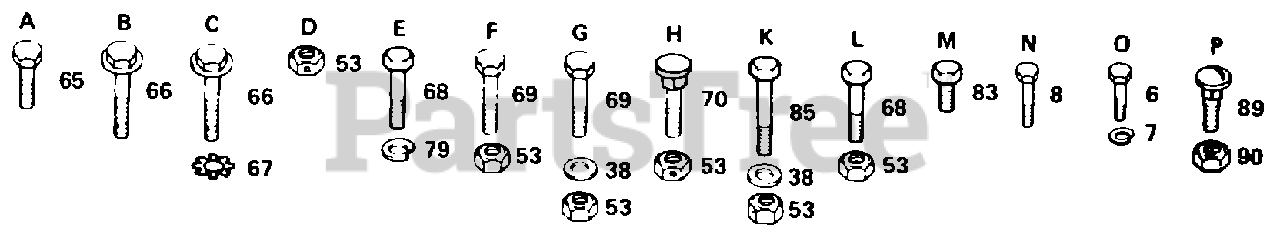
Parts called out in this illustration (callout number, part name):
6	BOLT
7	LOCKWASHER
38	WASHER
65	SCREW
66	SCREW LT
67	LOCKWASHER
69	BOLT
70	BOLT
79	LOCKWASHER
83	SCREW
85	BOLT
89	BOLT
